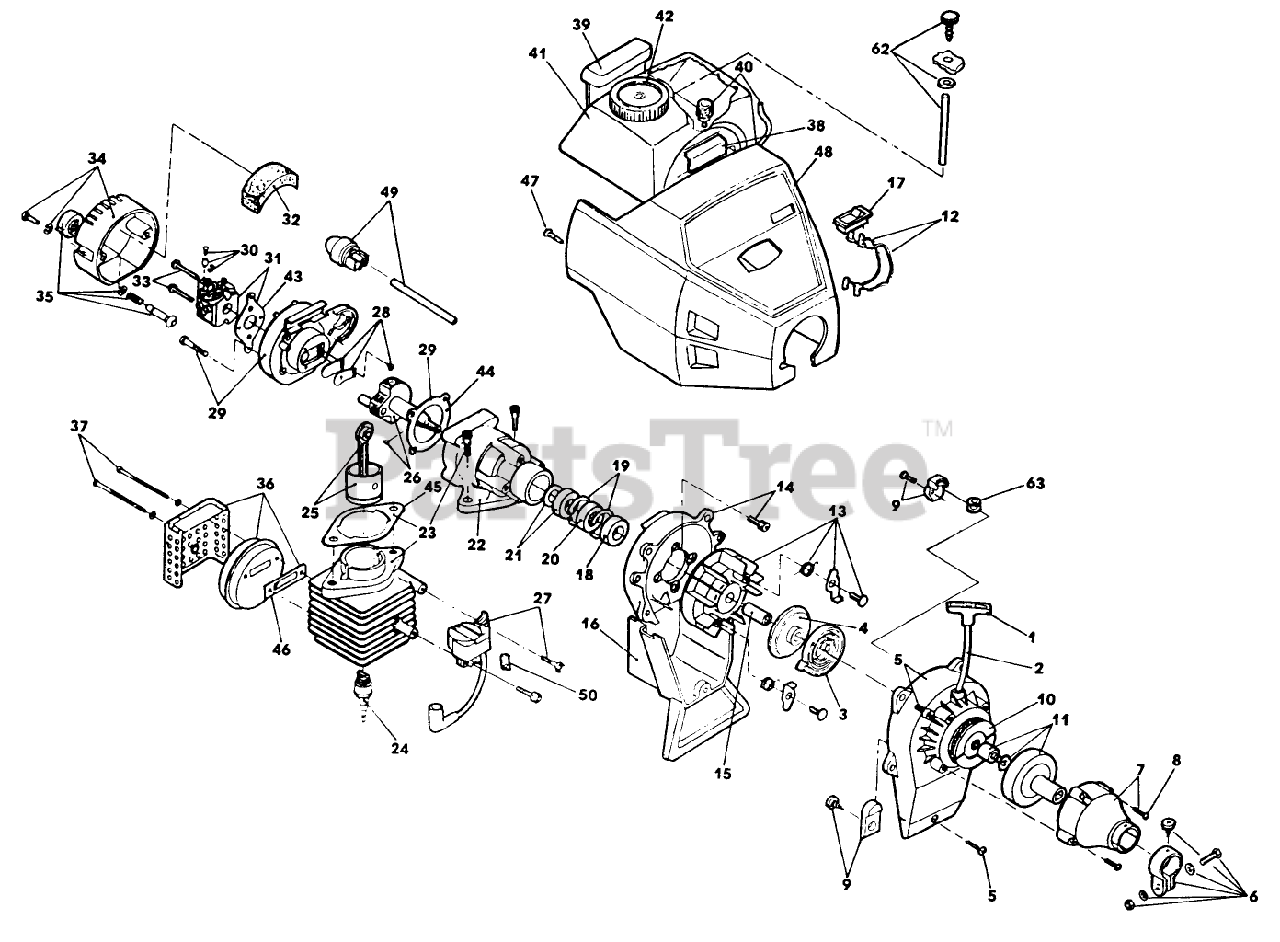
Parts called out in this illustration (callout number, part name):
3	RECOIL SPRING
6	CLAMP ASM - UPPER
14	SHROUD ASM
18	OUTER BEARING
21	INNER BEARING ASM
24	SPARK PLUG
30	THROTTLE ADJ ASM
37	MTNG BOLT ASM 2 PCS = 1
38	FRONT MOUNTING PAD
39	REAR MOUNTING PAD
40	FUEL LINE ASM
43	CARB.GASKET
62	FUEL RETURN LINE ASM
